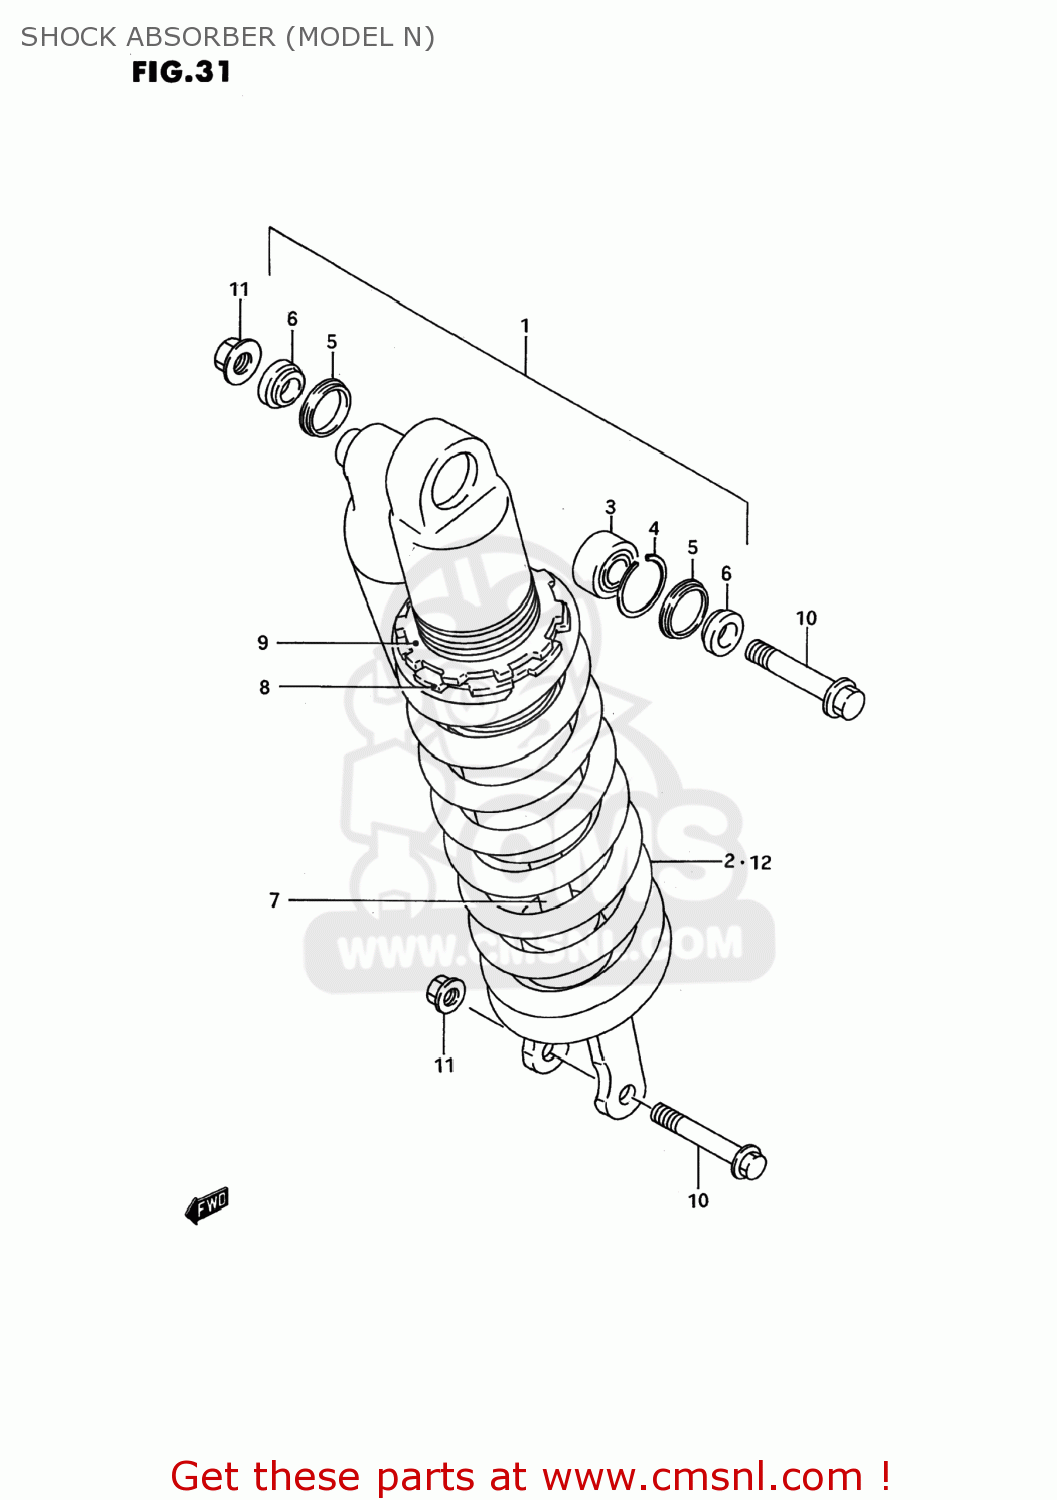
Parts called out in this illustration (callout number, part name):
1	ABSORBER ASSEMBLY,REAR SHOCK
2	SPRING
3	BEARING,RR CUSHION LEVER RR
4	RING,STOPPER
5	SEAL,DUST
6	COLLAR
7	ROD,PISTON
8	GUIDE,SPRING
9	NUT
10	BOLT,REAR SHOCK ABSORBER
11	NUT
12	SPRING
